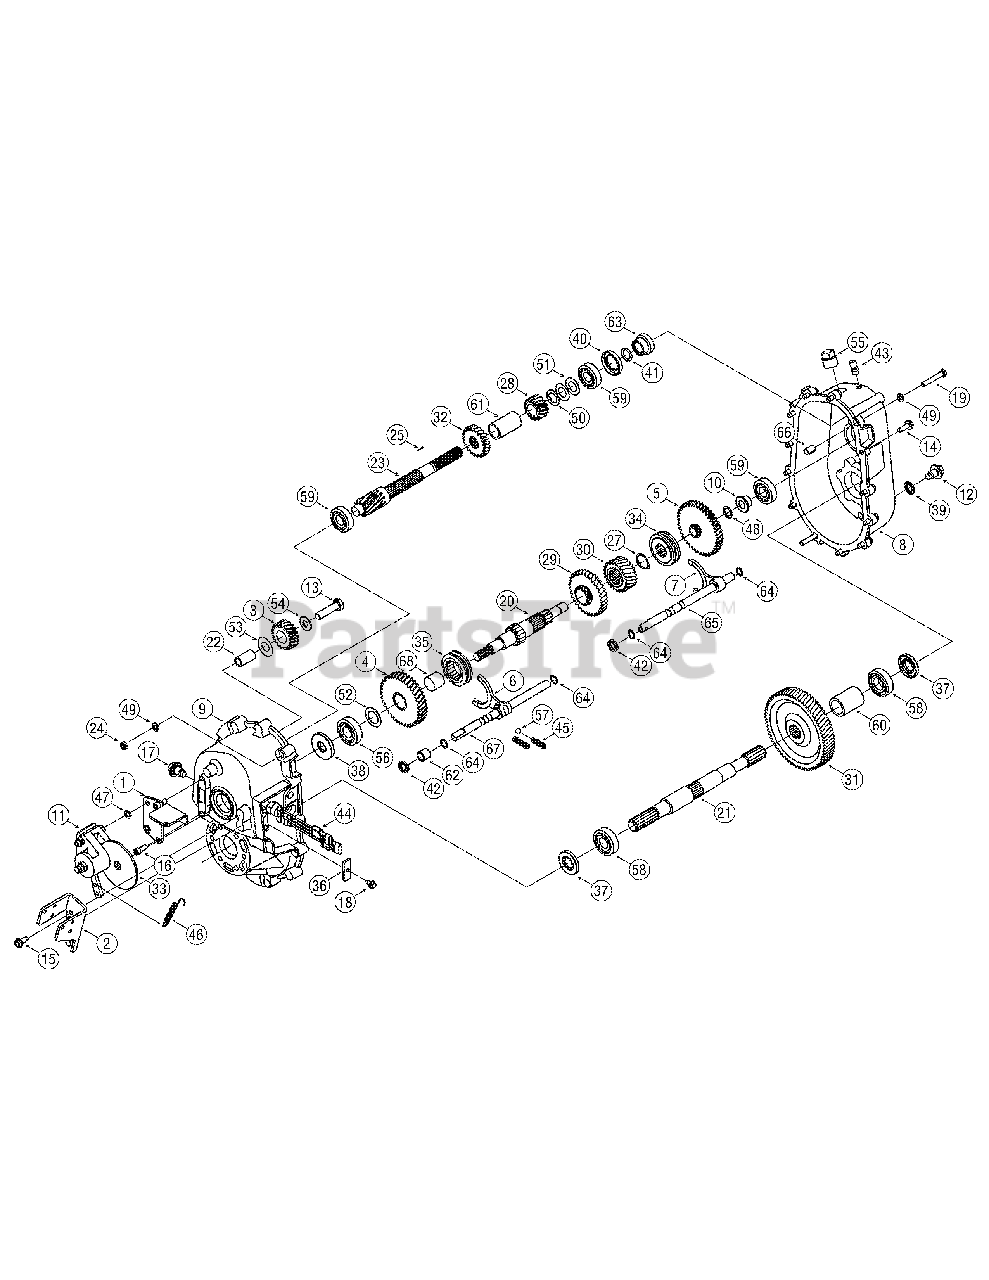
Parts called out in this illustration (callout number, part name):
1	Brkt Asm, Brk, Mnt, Painted
2	Brkt Asm, Shift, Trans, Painted
3	Gear Asm, Rev Idler
4	Gear, Rev, 39T
5	Gear Asm, Low Speed
6	Yoke, Actr, Uv
7	Yoke Actr, Lo
8	Hsg, Lh, Uv
9	Hsg, Rh, Uv
10	Spcr, Flg, .630 x .787 x .662
11	Brake Asm, Transfer Case
12	Scr, Plug, M14x1.5, Magnetic
13	Hhcs, 1/2-13, 2.00, Gr5, Lock
14	Scr, Tt, 5/16-18, 1.000, Hxindwsh
15	Scr, Tt, 5/16-18, 0.750, Hxindwsh
16	Scr, Soc Hd, 5/16-18, .750
17	Scr, Plug, M14x1.5 X .827
18	Scr, Tt, 1/4-20x.625, Hxindwsh
19	Hhcs, 5/16-18, 2.00, Gr5, Std
20	Shf, Mid, Transfer Case
21	Shf, Output, Transfer Case
22	Shf, Rev Idler
23	Shf, Input, Transfer Case
24	Nut, Hexlk, 5/16-18, Gra, Ctrlk
25	Pin, Roll, 1/8 Od, .63
26	Ext Snap Ring .625 Dia Shaft
27	Ring, Ret, 1.125 Dia Shaft
28	Gear, Low Pinion, 15t
29	Gear, High, 33t
30	Gear, Final Pinion, 22t
31	Gear, Final, 73t
32	Gear, Pnion, High, 22t
33	Disc, Brk, Uv
35	Colr, Hi-rev, 4x4
36	Plt, Detent Spring
37	Seal, Oil, 25x46x7
38	Seal, Oil, 20x52x7
39	Gskt, 14.15 X 24.6 X 1.5
40	Seal, Oil, 30 X 47 X 7
41	O-rg, .734 Id X .139
42	Seal, Oil, .563 X .875 X .188
43	Creeper Drive Housing Breather
44	Sw, Saf, Neut
45	Spr, 3/8 Od X 1 1/4 Lg
46	Spr, Extn, .38 Od X 3.9 Lg
47	Wash, Flat, .385 X .620 X .033
48	Wash, Flat, .635x.930x.033, Ht
49	Wash, Flat, .330 X .630 X .0635
50	Wash, Flat, .793 X 1.24 X .06, Ht
51	Wash, Flat, .793x1.368x.010, Ht
52	Wash, Flat, 1.007x1.542x.03, Ht
53	Wash, Thrust, .757 X 1.38 X .062
54	Wash, Flat, .51 X 1.12 X .06, Ht
55	Plug, Pipe, 3/4 Nptf
56	Brg, Ball, .79 Id X 2.05 Od X .6
57	Ball, Detent, .375
58	Brg, Ball, 25x52x15, 6205, Open
59	Brg, Ball, 20x47x14, 6204, Open
60	Spcr, Output Shaft
61	Spcr, Mid Shaft
62	Spcr, .566 X .725 X .650
63	Spcr, Input, Uv, Transfer Case
64	Ring, Ret
65	Shf, Actr, Lo
66	Dowel, Bush, .400 x .484 x .750
67	Shf, Actr, Fwd, Rev
68	Brg, Slv, 25mm x 28mm x 25mm
